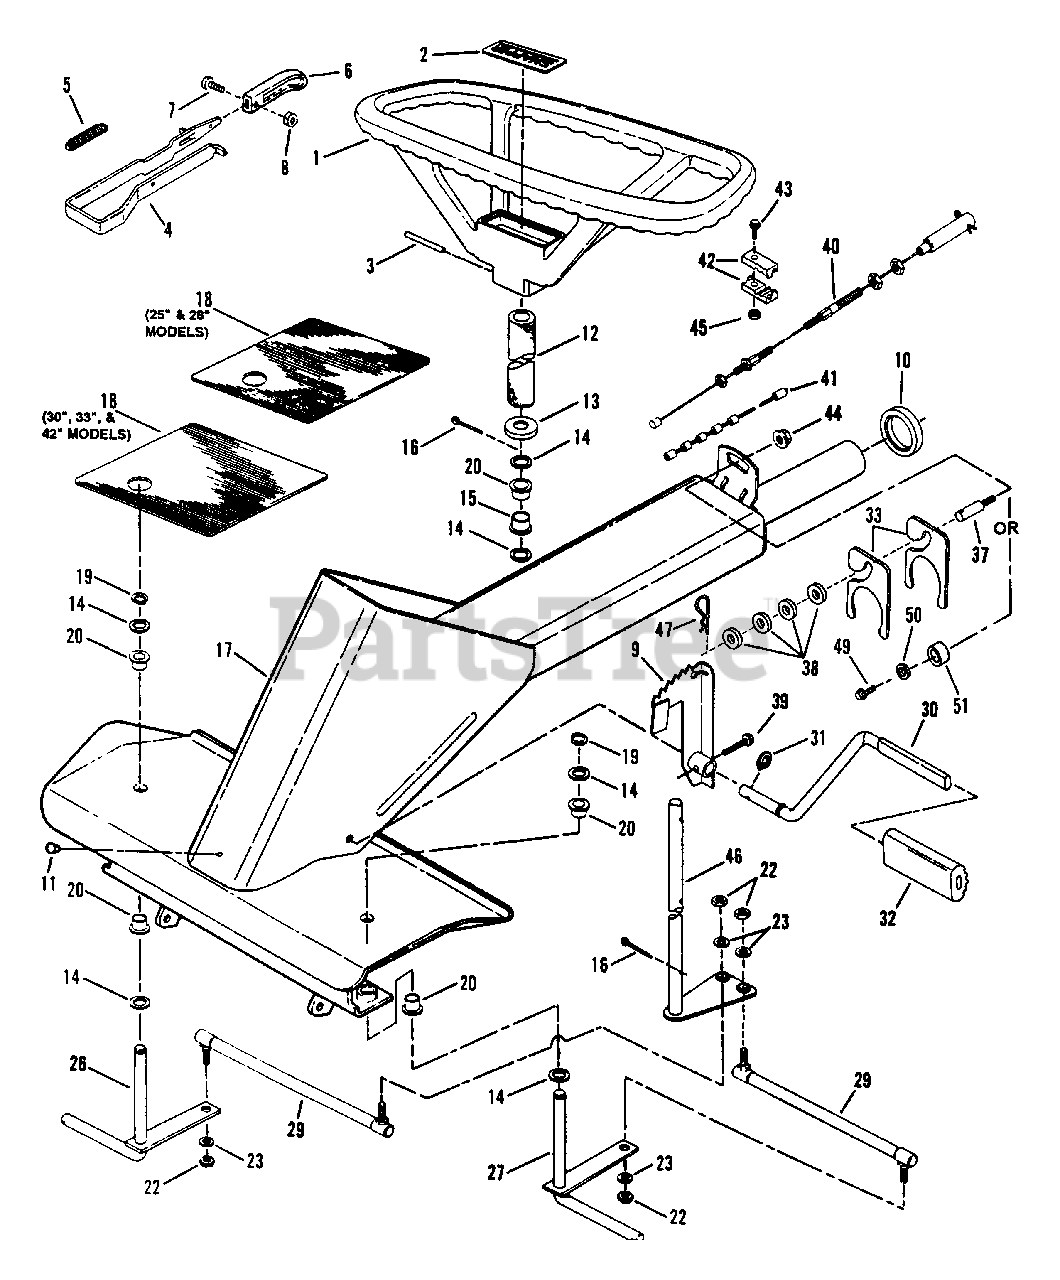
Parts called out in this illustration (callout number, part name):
1	ASSEMBLY, Steering Wheel
2	DECAL, Snapper
3	PIN, 1/4 x 1-1/2" Roll
4	BRACKET, Clutch/Brake
5	SPRING
6	KNOB
7	SCREW, #8-32 x 3/8" Cross Recess
8	NUT, #8-32 Hex
9	ARM, Clutch/Brake
10	SPACER, Main Tube
11	PLUG
12	COVER, Steering Shaft (Foam)
13	COVER
14	WASHER, 3/4 Flat
15	BUSHING, 3/4" Steering Shaft
16	PIN, 3/16 x 1-1/2" Cotter
17	FRAME, Front
18	PAD, Foot (Right Side)
19	RING, Retaining
20	BEARING
22	NUT, 5/16-24 Hex
23	WASHER, 5/16 Split Lock
26	PIN, Wide King (Right Side)
27	PIN, Wide King (Left Side)
29	TIE-ROD
30	PEDAL, Clutch/Brake
31	RING, 5/8" External Retaining
32	PAD, Clutch/Brake Pedal
33	SPACER, Pivot
37	STUD, 3/8-24 x 5/8" Shoulder
38	SPACER
39	SCREW, 5/16-18 x 1-1/4" Self-Tapping
40	CABLE, Brake
41	CABLE, Clutch
42	UNION, Cable
43	BOLT, 1/4-20 x 3/4" Hex Flange Lock
44	NUT, 3/8-16 Hex Nylock
45	NUT, 1/4-20 Hex Center Lock
46	SHAFT, Steering (Wide Front End)
47	PIN, 1/8 x 2-9/16" Hair
49	SCREW, 3/8-16 x 5/8 Self Tapping
50	WASHER, 3/8" Flat
51	SPACER, .39 x .625 x .19
